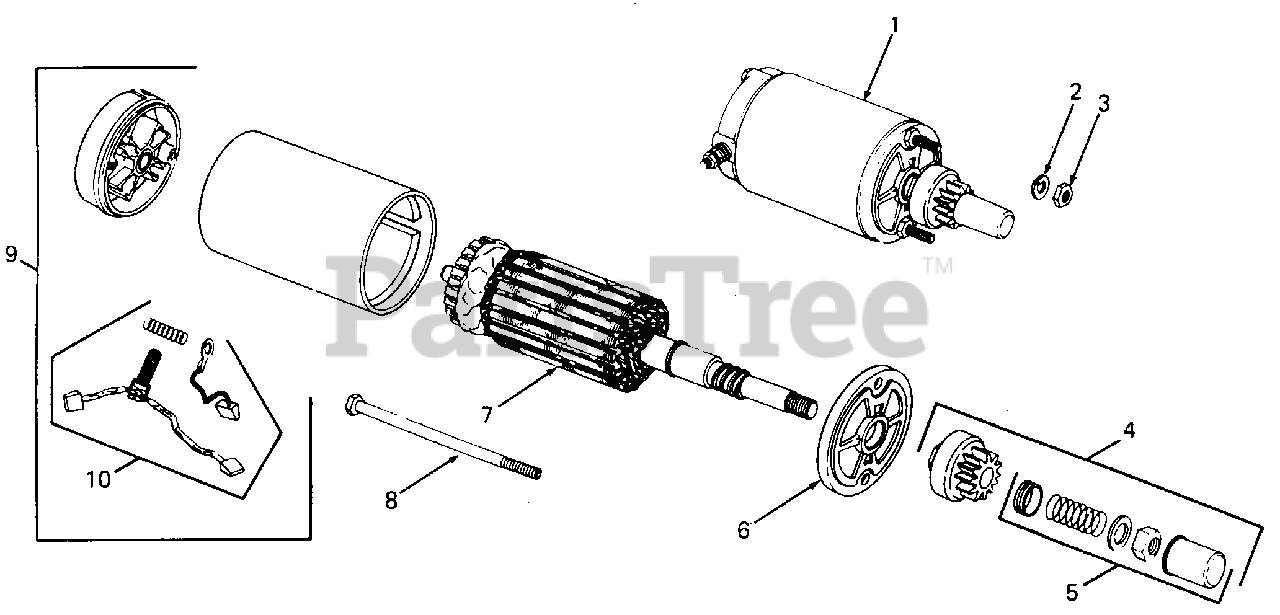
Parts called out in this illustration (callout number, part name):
1	Starter Assembly
2	Washer, Lock, 1/4
3	Nut, Hex, 1/4-20
4	Kit, Drive
5	Kit, Drive Parts
6	Cap, Drive End
9	Cap, Commutator End
10	Kit, Brush
